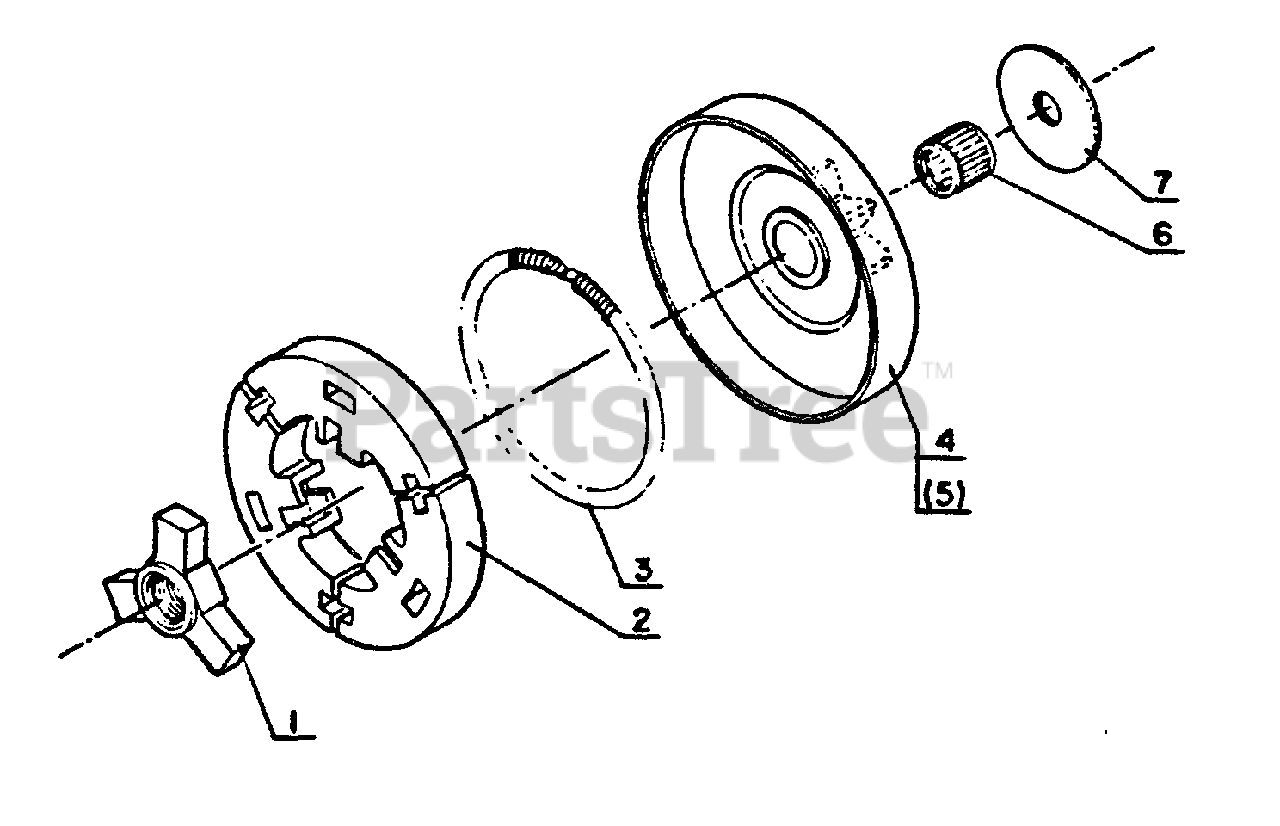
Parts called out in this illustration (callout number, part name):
1	HUB, CLUTCH
2	SHOE, CLUTCH
3	SPRING, CLUTCH
4	CASE, CLUTCH
6	BEARING, NEEDLE
7	WASHER, CLUTCH
